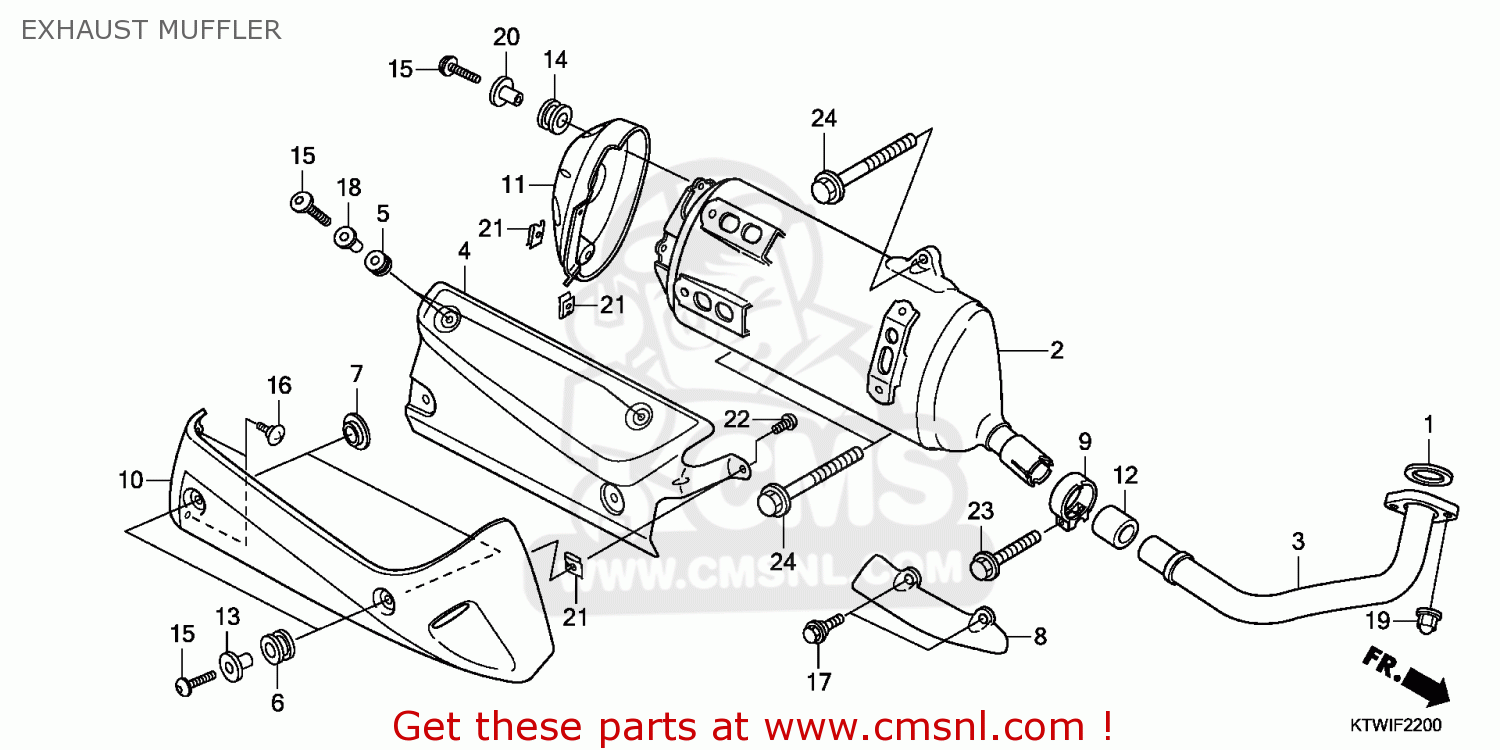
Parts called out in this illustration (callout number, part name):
1	GASKET,EX.PIPE (NAS)
2	MUFFLER COMP,EXH
3	PIPE COMP,EXH
4	PROTECTOR A,MUFF.
5	RUBBER,PROTECTOR
6	RUBBER,PROTECTOR
7	COLLAR,PROTECTOR
8	PROTECTOR,EXH.PIP
9	BAND,EX.PIPE
10	PROTECTOR SUB ASS
11	COVER SUB ASSY,TA
12	PACKING,MUFFLER (NAS)
13	COLLAR TANK SET.
14	RUB,RR FENDER MT
15	SCREW,PAN 5X20
16	SCREW,SPECIAL,5MM
17	BOLT,SPECIAL M6
18	COLLAR,REFLEC.SET
19	NUT,CAP,8MM
20	WASHER,FR.COVER
21	NUT,CLIP 5MM
22	SCREW,CROSS,5X12
23	BOLT,FLANGE,8X35
24	BOLT,FLANGE,10X50
